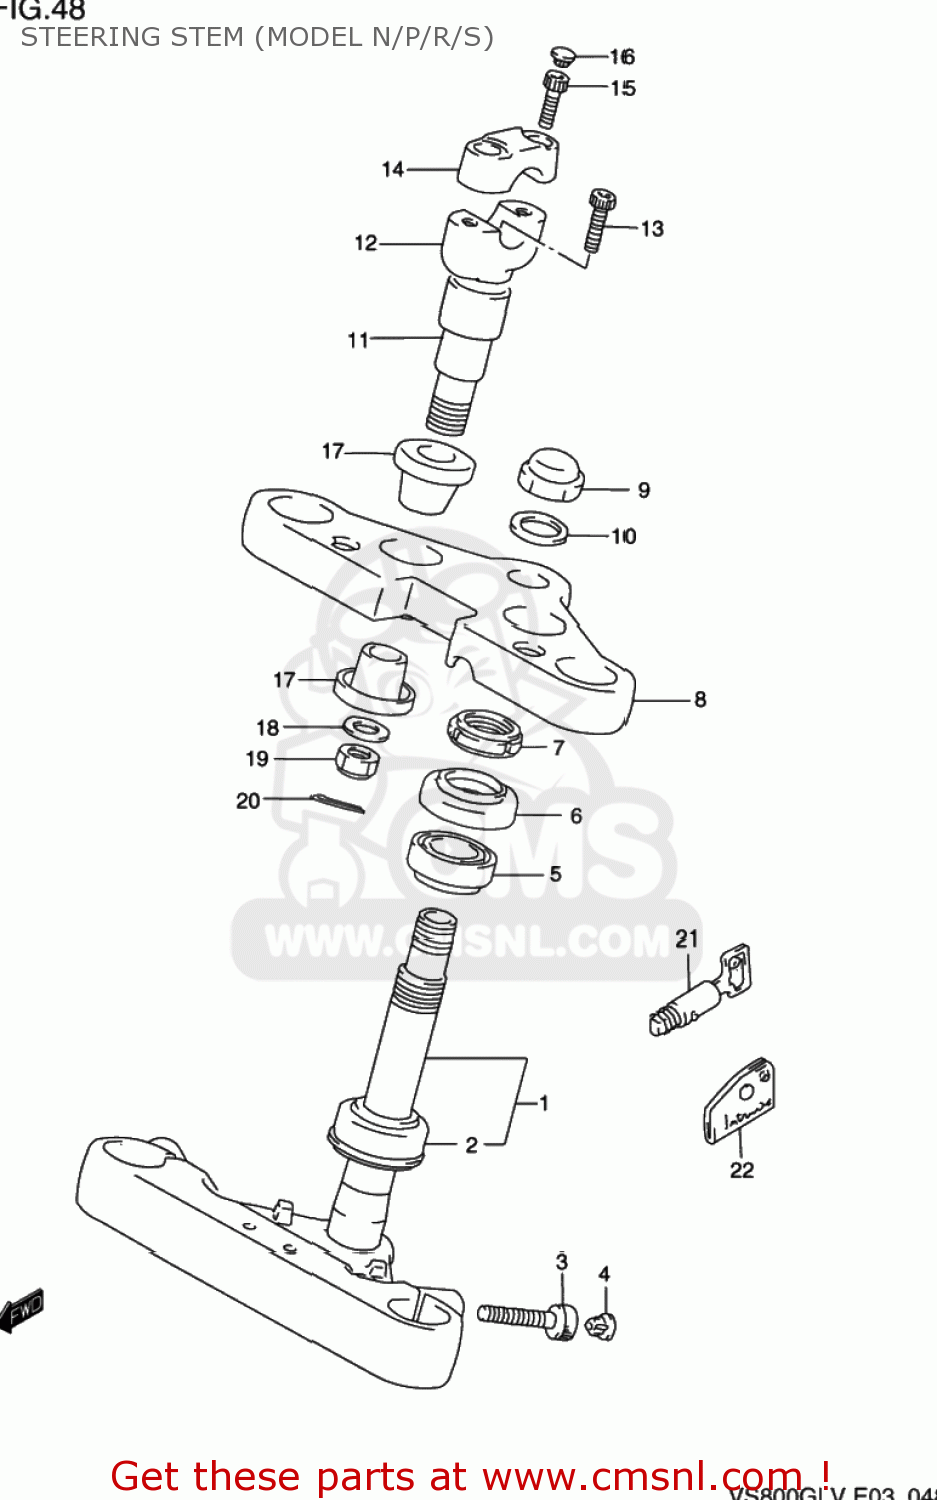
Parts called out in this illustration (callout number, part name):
1	STEM,STEERING
2	BEARING(30X55X17)
3	BOLT,STEERING STEM HEAD
4	CAP(OD:12)
5	TAPER,ROLLER BEARING
6	SEAL,STEERING UPR DUST
7	NUT,STEERING STEM(25X44X10)
8	BRACKET,UPR
9	NUT,CAP
10	WASHER
11	STAY,HANDLE
12	HOLDER,HANDLE LWR
13	BOLT
14	HOLDER,HANDLE UPR
15	BOLT, REAR (8X30)
16	CAP(OD:14.5)
17	CUSHION
18	WASHER
19	NUT
20	PIN
21	LOCK SET,STEERING
22	CASE,STEERING KEY
